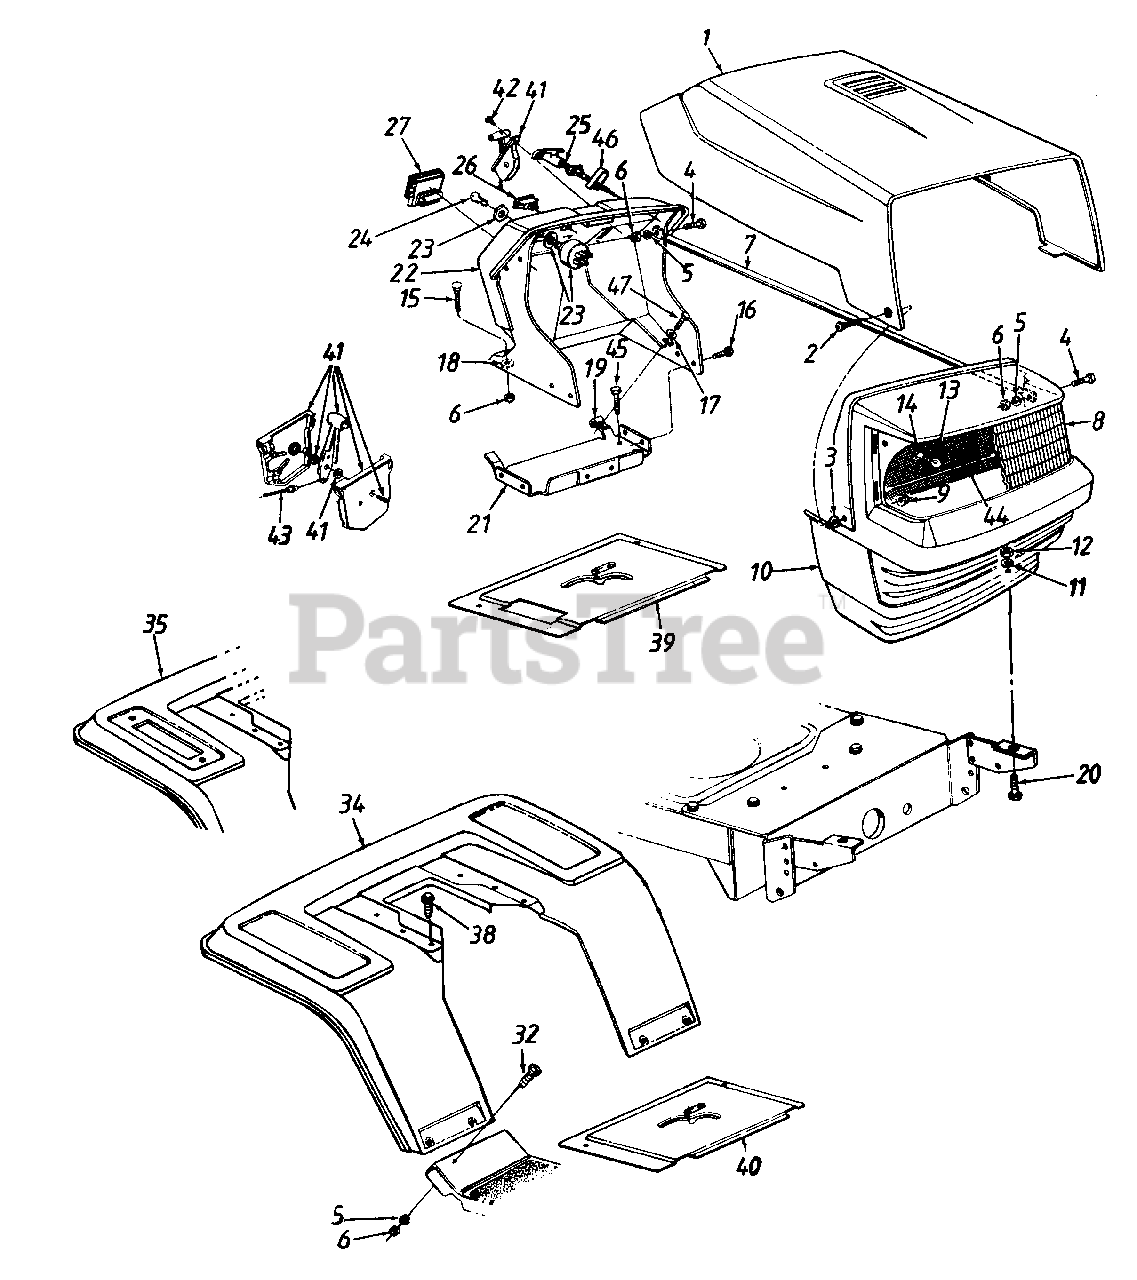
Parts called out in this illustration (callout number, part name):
3	Fl-Wash. .28" I.D. x .75" O.D.
4	Hex Bolt 1/4-20 x .62" Lg.
5	L-Wash. 1/4" I.D.
6	Hex Nut 1/4-20 Thd.
8	Headlight Lens
9	Flange L-Nut 1/4-28 Thd.
10	Grille
11	Fl-Wash. .344" I.D. x 1" O.D.
12	Hex Nut 5/16-18 Thd.
13	Lamp
14	Socket
15	Carriage Bolt 1/4-20 x .75" Lg.
16	Hex Wash. Hd. TT-Tap Scr. 1/4-20 x .5" Lg.
17	Fl-Wash. .281" I.D. x .73" O.D.
18	Bolt Retainer 1/4" I.D.
19	Speed Nut 1/4-20 Thd.
20	Hex Bolt 5/16-18 x .75" Lg.
23	Ignition Switch
24	Ignition Key
25	Choke Control
26	Light Switch
27	Ammeter
32	Truss Mach. Scr. 1/4-20 x .5" Lg.
41	Throttle Box Ass'y.
42	Truss Mach. AB-Tap Scr. #10 x .5" Lg.
43	Throttle Control Wire
44	Grille Reflector Label
45	Hex Wash. Hd. B-Tap Scr. 5/16-18 x .5" Lg.
46	Choke Retainer
47	Hex TT-Tap Scr. 1/4-20 x .75" Lg.
17870-0498	FENDER-RR W/FRAME - OLD CUB YELLOW (0498)
17870-0638	FENDER-RR W/FRAME - MTD/TROY-BILT RED (0638)
17870-0667	FENDER-RR W/FRAME - MIDNIGHT BLUE (0667)
